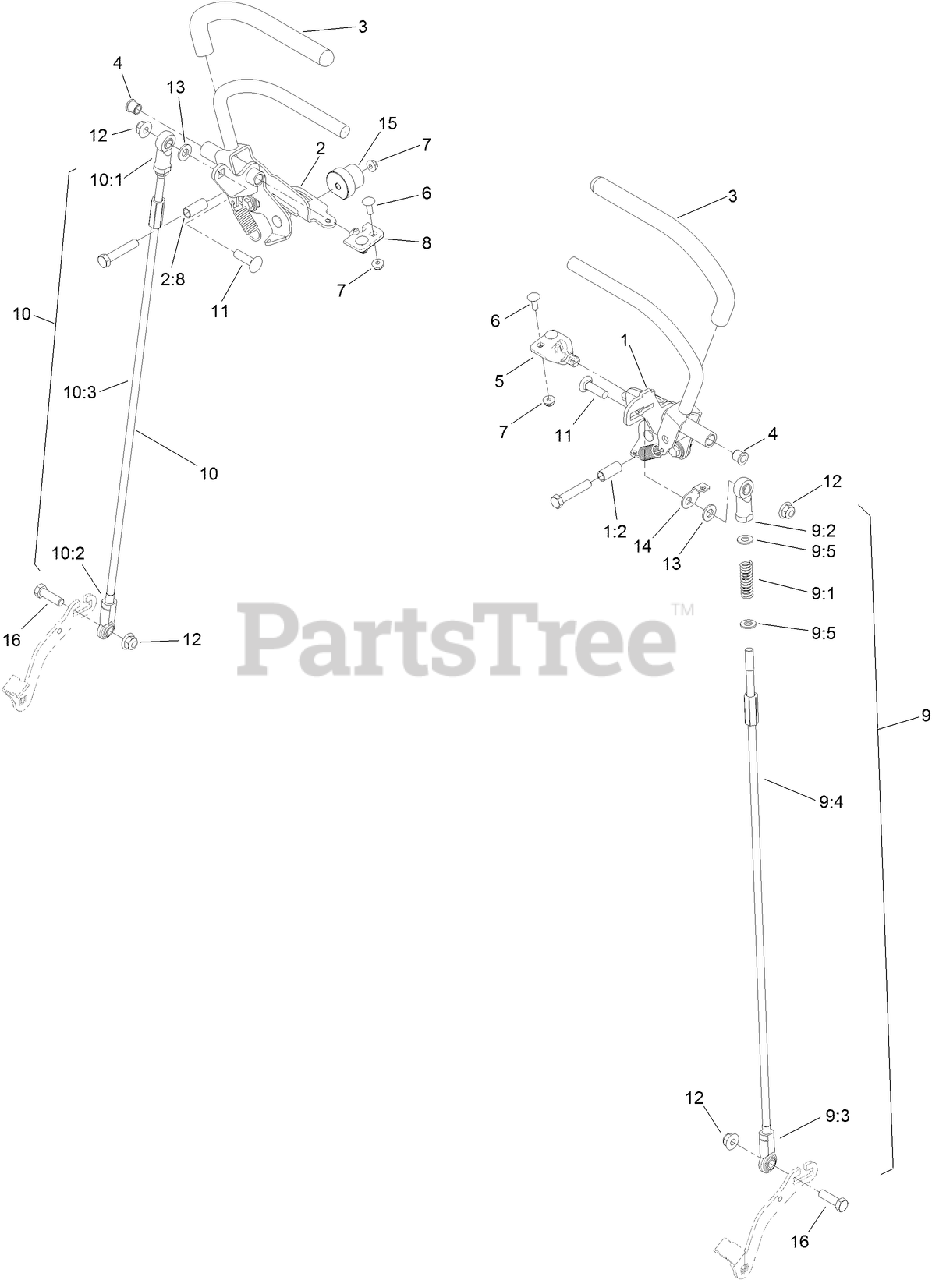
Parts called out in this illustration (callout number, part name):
1	LH CONTROL HANDLE ASM
1:2	BEARING-SLEEVE
2	RH CONTROL HANDLE ASM
2:8	BEARING-SLEEVE
4	BEARING
5	TAB-PIVOT, LH
6	BOLT-CARR
7	NUT-HF
8	TAB-PIVOT, RH
9	LH CONTROL ROD ASM
9:1	SPRING-RETURN, NEUTRAL
9:2	END-ROD, FEMALE
9:3	JOINT-BALL END, LH
9:4	ROD-CONTROL
9:5	WASHER-FLAT
10	RH CONTROL ROD ASM
10:1	END-ROD, FEMALE
10:2	JOINT-BALL END, LH
10:3	ROD-CONTROL
11	SCREW-CARR
12	NUT-HF, NI
13	WASHER-FLAT
14	BRACKET-ADJUSTMENT, SPEED
16	SCREW-HH
